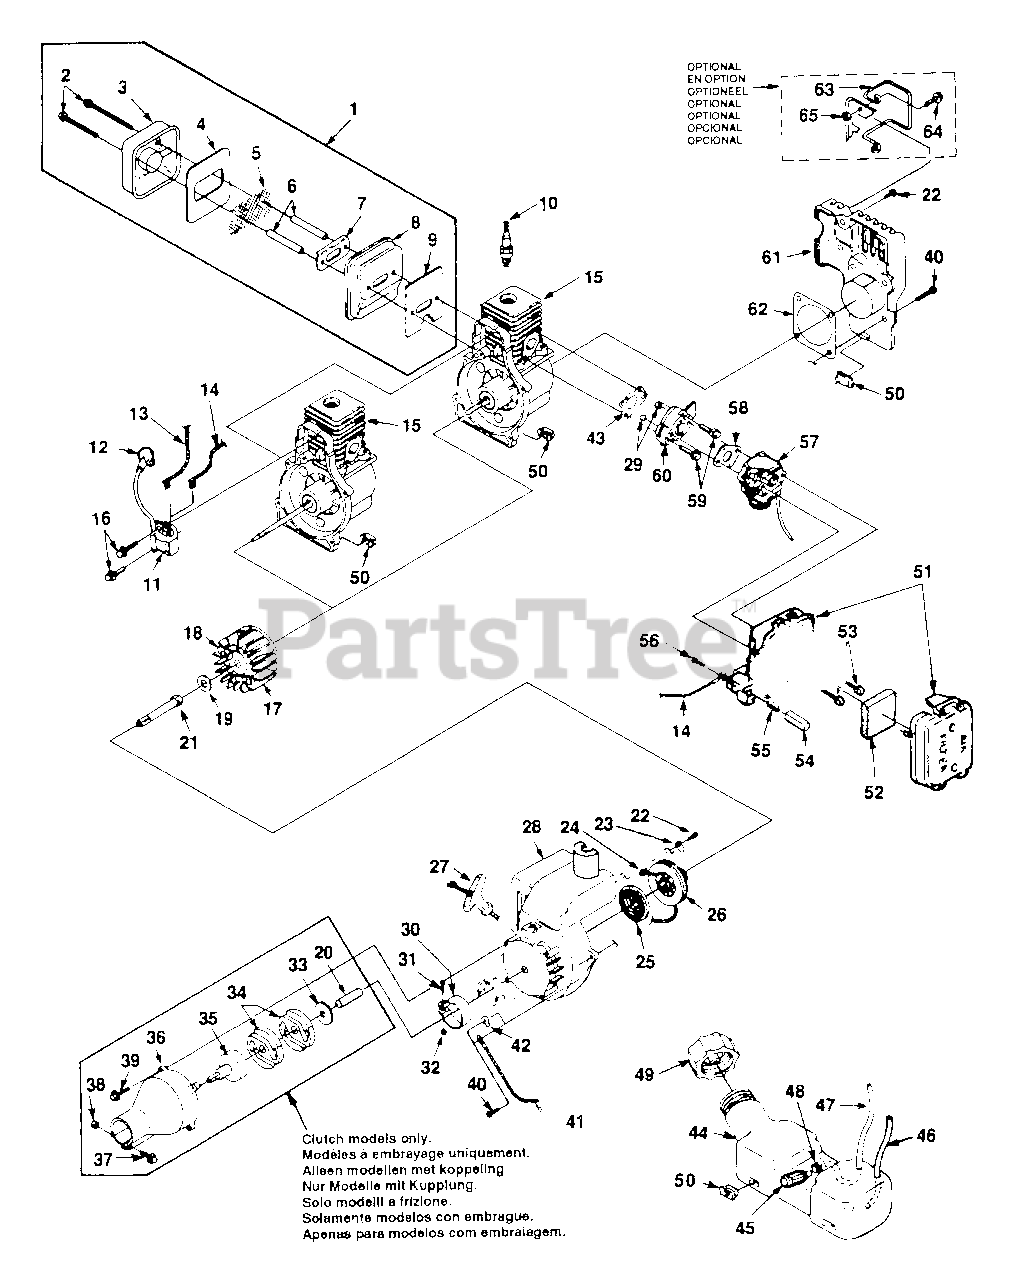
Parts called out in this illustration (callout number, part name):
1	MUFFLER-Complete
2	SCREW-Sems Hex Hd (10-24 X 2 1/2")
3	COVER-Muffler
4	BAFFLE-Muffler
5	SCREEN-Spark
6	SPACER-Muffler
7	PLATE-Reinforcing
8	BODY-Muffler
9	GASKET-Muffler
10	SPARK PLUG (RDJ7Y)
11	MODULE-Ignition
12	TERMINAL-Hi Tension
13	LEAD-Electrical
14	LEAD-Electrical
15	SHORT BLOCK
16	SCREW-Taptite (8-32 X 1")
17	ROTOR KIT
18	KIT-Starter Pawl
19	WASHER-Flat
19	WASHER-Flat (5/16")
20	SPACER
21	CONNECTOR-Drive
22	SCREW-Plastite (#10 X 1/2")
23	BRACKET-Retaining
24	ROPE-Starter (42")
25	SPRING & CONTAINER
26	PULLEY-Starter
27	GRIP-Starter
28	HOUSING-Engine
29	NUT-Hex (10-24)
30	CLAMP
31	SCREW-Hex Sems (10-24 X 3/8")
32	NUT-Square
33	WASHER-Clutch
34	CLUTCH
35	CONNECTOR & DRUM
36	TUBE ADAPTOR
37	SCREW-Sems Hex Hd (10-24 X 1 1/4")
38	NUT (10-24)
39	SCREW-Sams Hex Hd (10-24 X 7/8")
40	SCREW-Taptite (10-24 X 3/4")
41	LEAD-Ground
42	TERMINAL
43	GASKET-Heat Dam
44	TANK-Fuel
45	FILTER-Fuel
46	TUBING-Rubber (8")
47	TUBING-Rubber (8")
48	CLAMP-Wire
49	FUEL CAP
50	BUMPER-Rubber
51	AIR FILTER BOX
52	FILTER-Air
53	SCREW- Mach (10-24 X 2 1/4")
54	BUTTON-Switch
55	SPRING-Compression
56	SCREW-Plastite (#6)
57	CARBURETOR KIT
58	GASKET-Carburetor
59	SCREW-Taptite (10-24 X 1")
60	HEAT DAM
61	CRANKCASE COVER-Flocked
62	GASKET-Crankcase Cover
63	WIRE GUARD KIT
64	SCREW-Hex Sems (10-24 X 1/2")
65	NUT (10-24)
